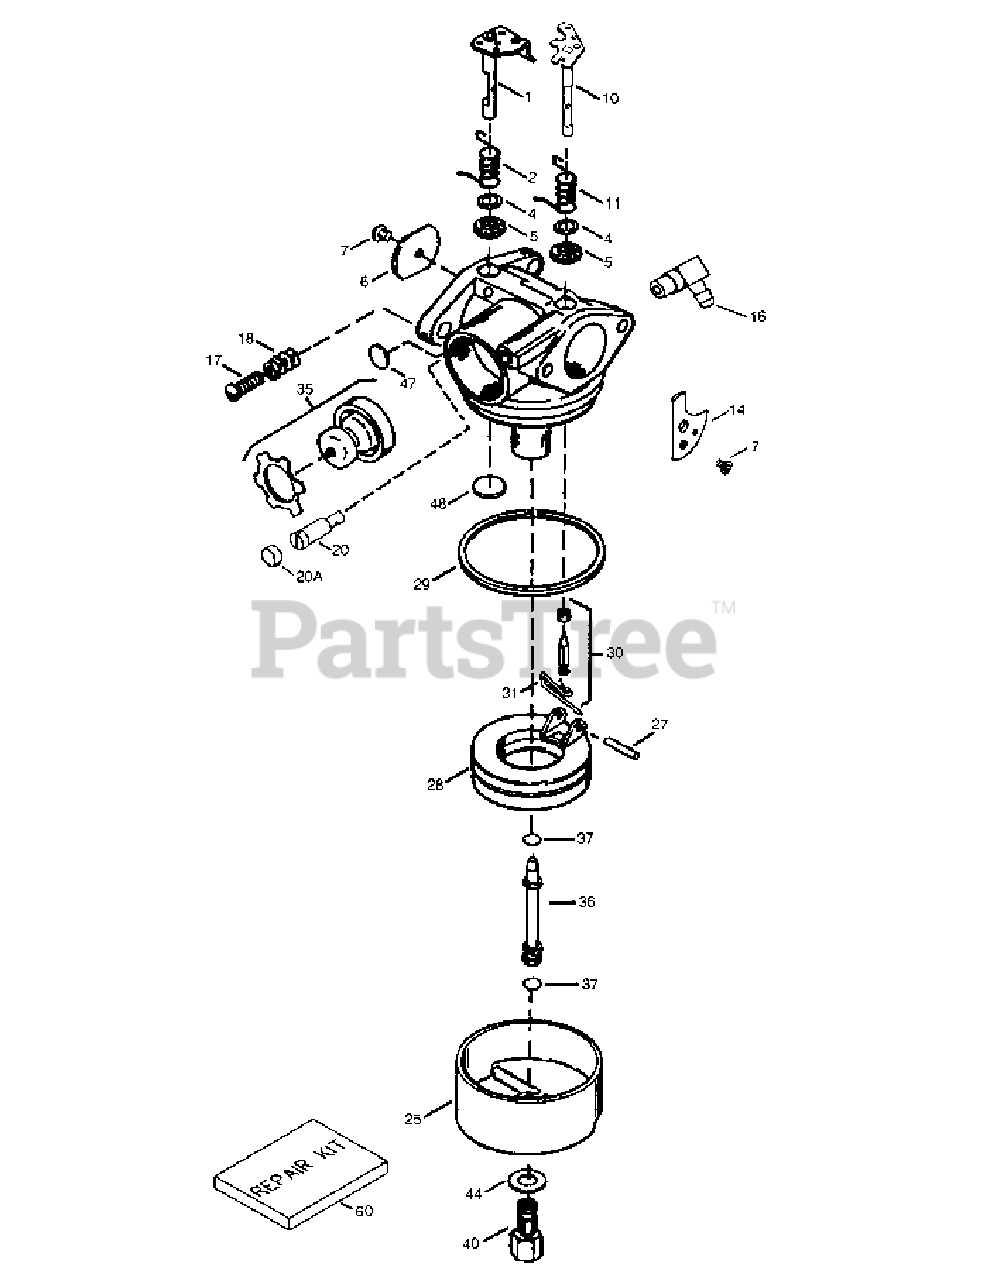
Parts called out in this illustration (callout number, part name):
1	Throttle Shaft & Lever Assembly
2	Throttle Return Spring
4	Dust Seal Washer
6	Throttle Shutter
7	Shutter Screw
10	Choke Shaft & Lever Assembly
11	Choke Return Spring
14	Choke Shutter
16	Fuel Fitting
17	Throttle Crack Screw/Idle Speed Screw
18	Tension Spring
20	Idle Restrictor Screw
20A	Idle Restrictor Screw Cap
25	Float Bowl
27	Float Shaft
28	Float (Plastic)
29	Float Bowl "O" Ring
30	Inlet Needle, Seat, & Clip (Incl. 31)
31	Spring Clip
35	Primer Bulb (Red) & Retainer Ring
36	Main Nozzle Tube
36A	Bowl Vent Tube Extension
37	"O" Ring, Main Nozzle Tube
40	High Speed Bowl Nut
44	Bowl Nut Washer
47	Welch Plug, Idle Mixture Well
48	Welch Plug, Atmospheric Vent
60	Repair Kit
